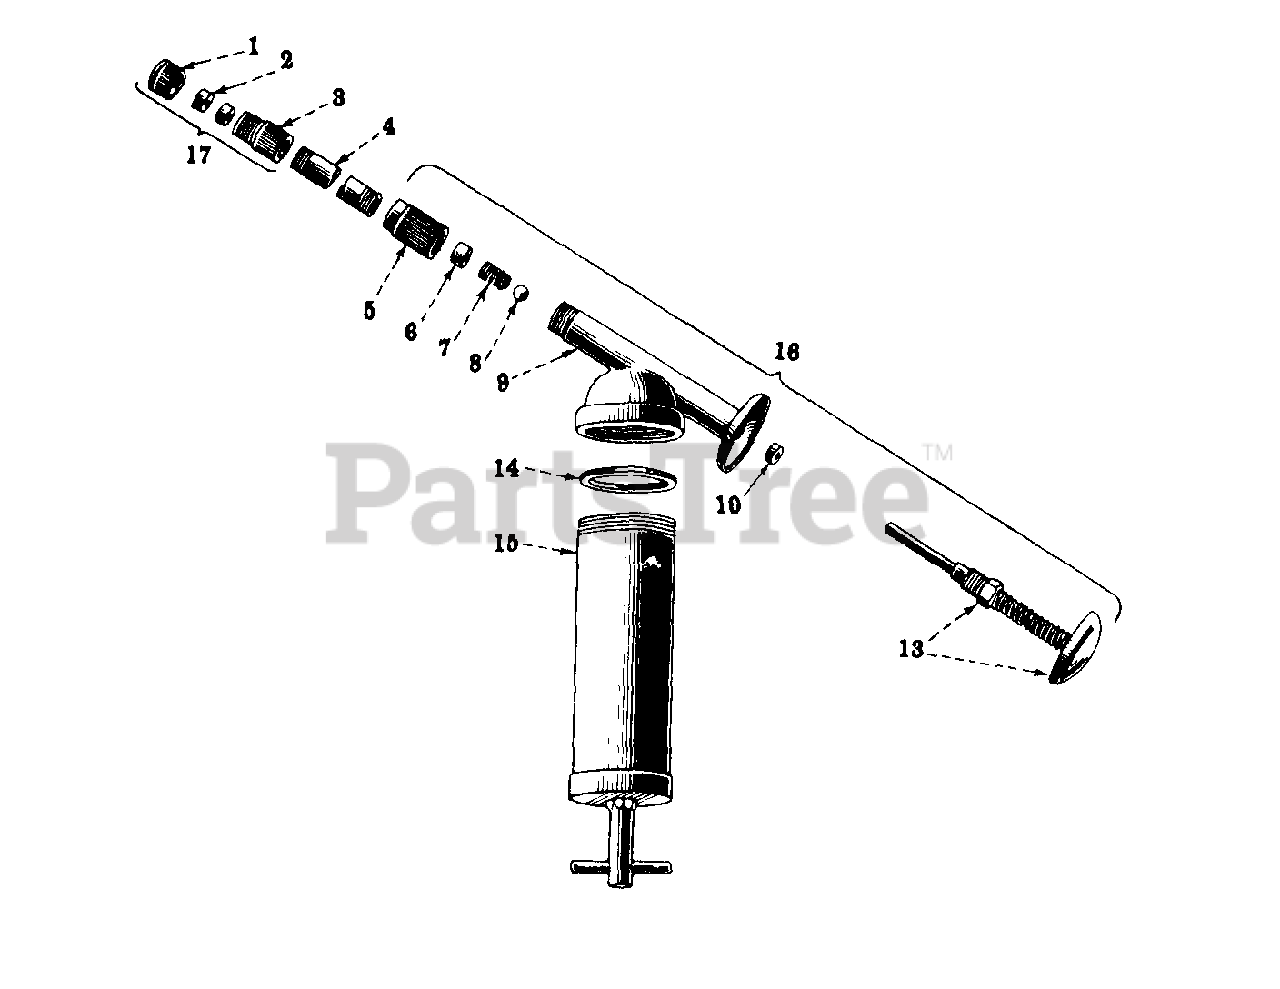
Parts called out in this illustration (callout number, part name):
1	CAP
2	WASHER SET OF TWO
3	BODY NOZZLE
4	PIPE 1/8 X 3 STANDARD
5	ADAPTER W/INSERT
6	PACKING ADAPTER
7	SPRING
8	BALL, CHECK
9	BODY
10	PACKING, PLUNGER
13	PLUNGER
14	GASKET
15	CONTAINER
16	HEAD ASSY
17	NOZZLE W/CAP AND WASHERS
